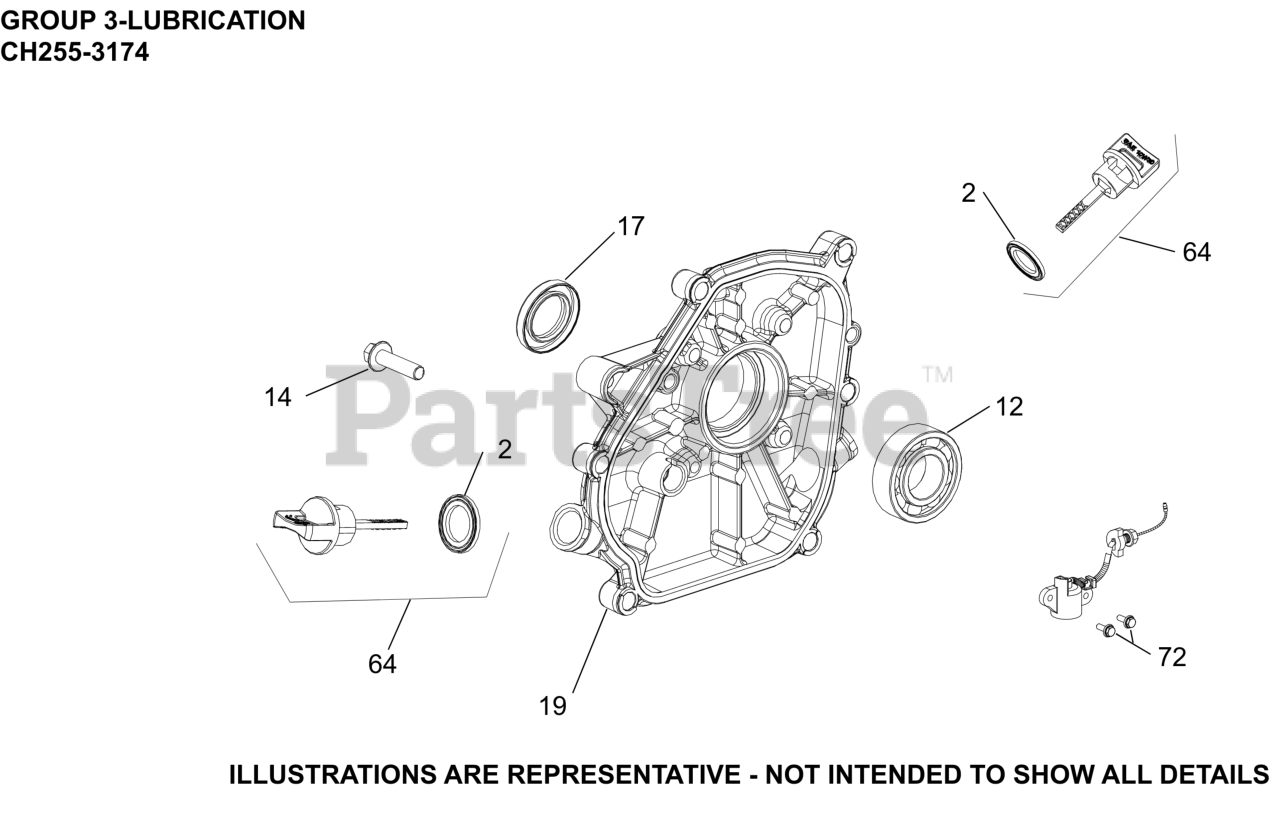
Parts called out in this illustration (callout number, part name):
2	SEAL, DIPSTICK
12	BEARING, BALL
14	SCREW, CLOSURE PLATE
17	SEAL - USE 17 032 29-S
19	PLATE, CLOSURE & BEARING
64	DIPSTICK ASSEMBLY
72	SCREW, M6 X 16
